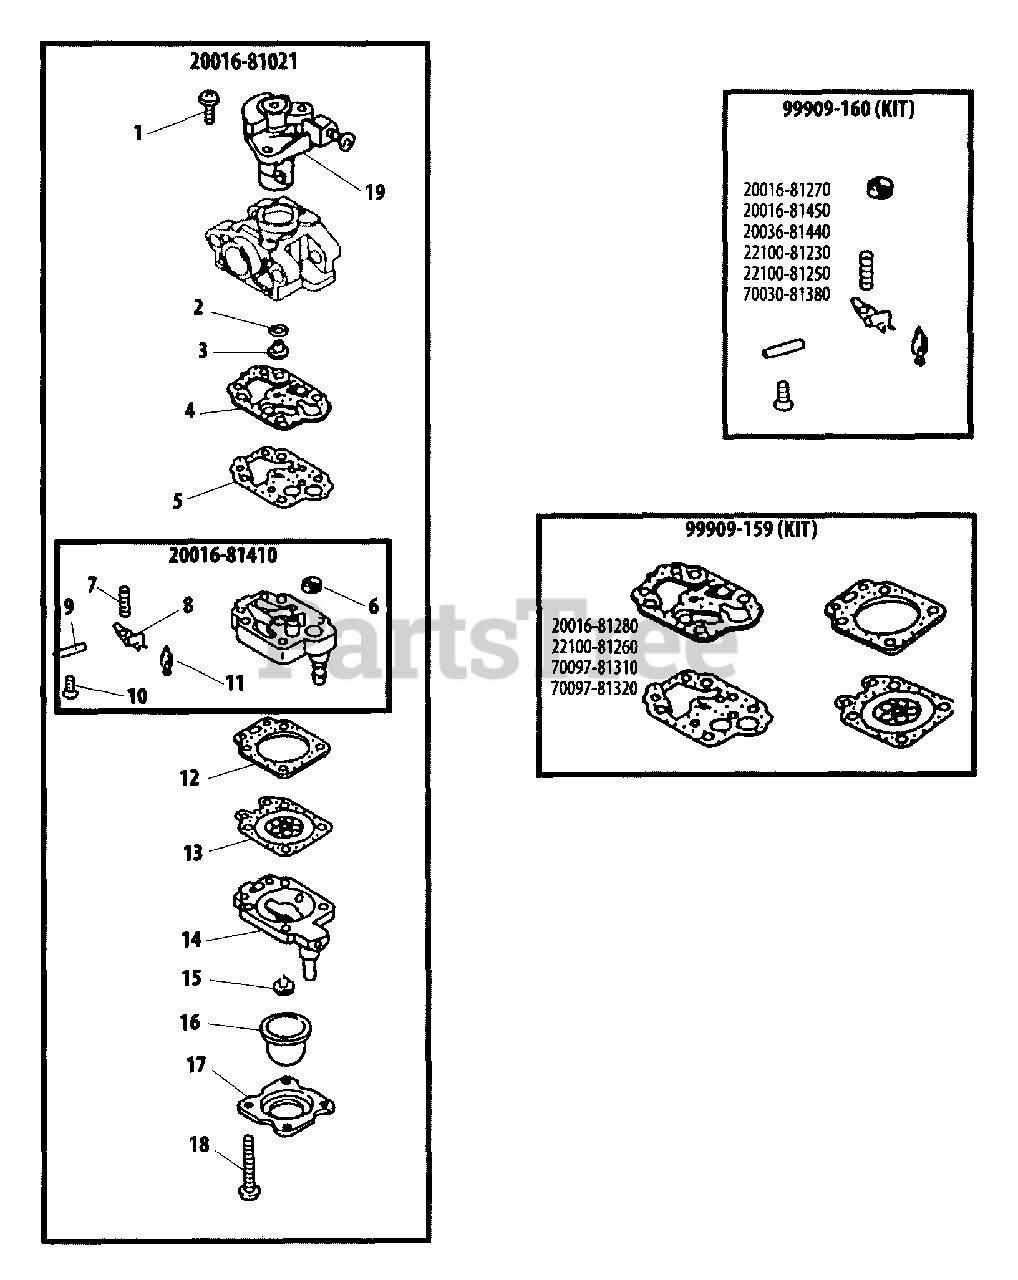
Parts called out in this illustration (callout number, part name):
1	SCREW
2	O-RING
3	JET, MAIN
4	GASKET, PUMP
5	DIAPHRAGM, PUMP
6	STRAINER
7	SPRING, METERING LEVER
8	LEVER, METERING
9	PIN, METERING LEVER
10	SCREW, METERING LEVER PIN
11	VALVE, INLET NEEDLE
12	GASKET, METERING
13	DIAPHRAGM, METERING
14	BASE, PURGE
15	VALVE, CHECK
16	BULB, PURGE
17	RETAINER, PURGE BULB
18	SCREW, PUMP COVER
19	VALVE, THROTTLE
20016-81021	CARBURETOR
20016-81410	PUMP BODY ASSY
99909-159	DIAPHRAGM/GASKET KIT
99909-160	REPAIR KIT
